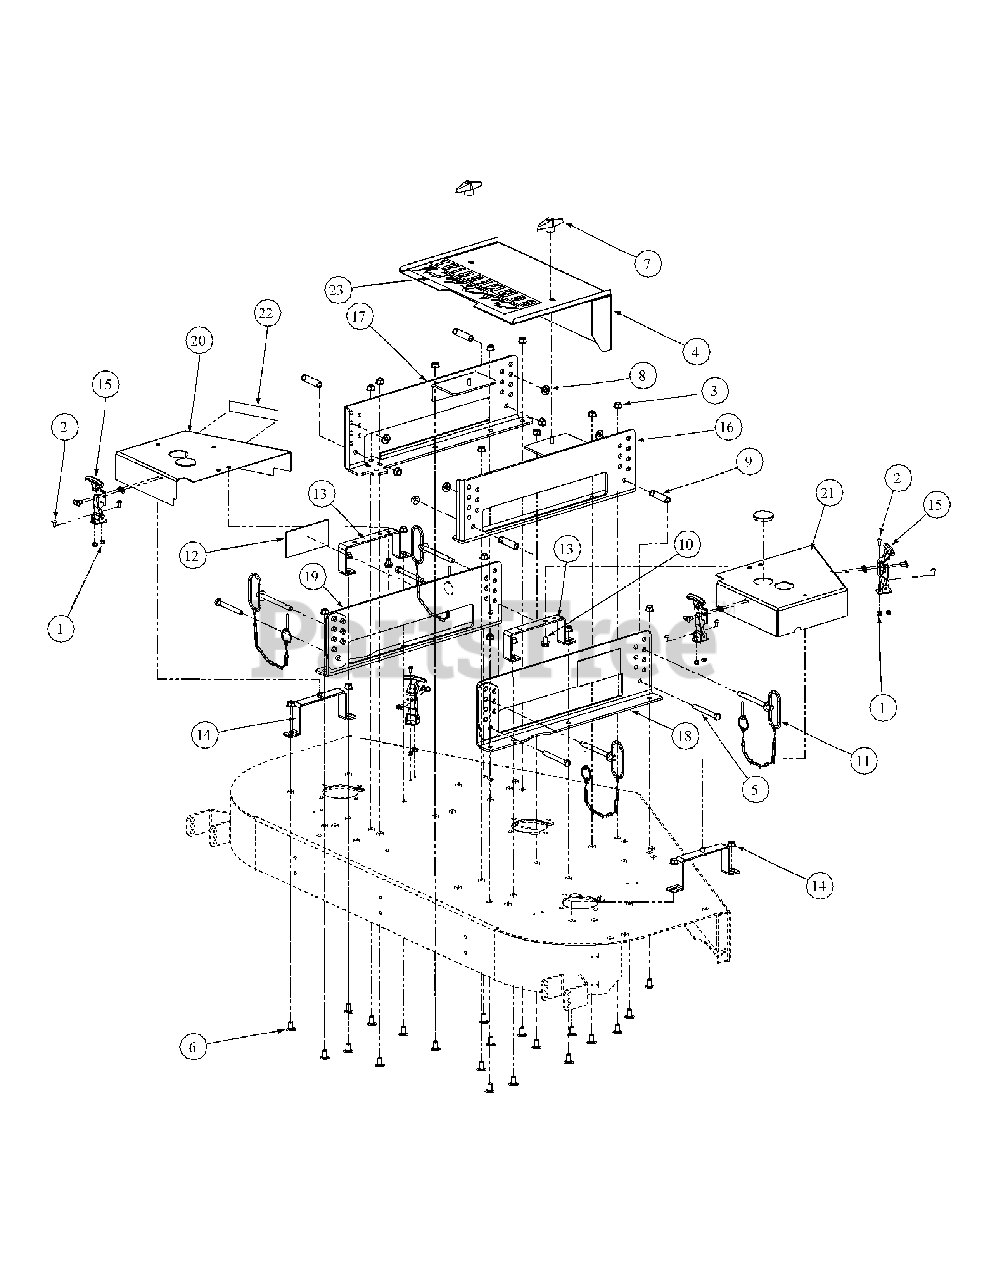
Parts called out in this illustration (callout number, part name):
1	Lock Nut Nylon Insert, 10-32
2	Machine Screw, 10-32 x 1/2
3	Flange Lock Hex Nut, 3/8-16
4	Center Belt Cover
5	Hex Cap Screw, 3/8-16, 3.25
6	Carriage Bolt, 3/8-16 x .75 Lg.
7	Wingnut Knob Assembly, 5/16-18
8	Flat Washer, .385 ID x .870 OD x .092
10	Hex Index Washer Screw, 3/8-16, .5
11	Deck Pin, 3/8 Dia.
12	Label, Height of Cut
13	Belt Cover Support
14	Outer Belt Cover Support
15	Draw Latch T-Handle
16	Inner Hanger Assembly, RH
17	Inner Hanger Assembly, LH
18	Outer Hanger Assembly, RH
19	Outer Hanger Assembly, LH
20	Belt Cover Weldment, LH
21	Belt Cover Weldment, RH
22	Label, Mower Deck, HF1748
23	Label, Commercial Mower Deck
